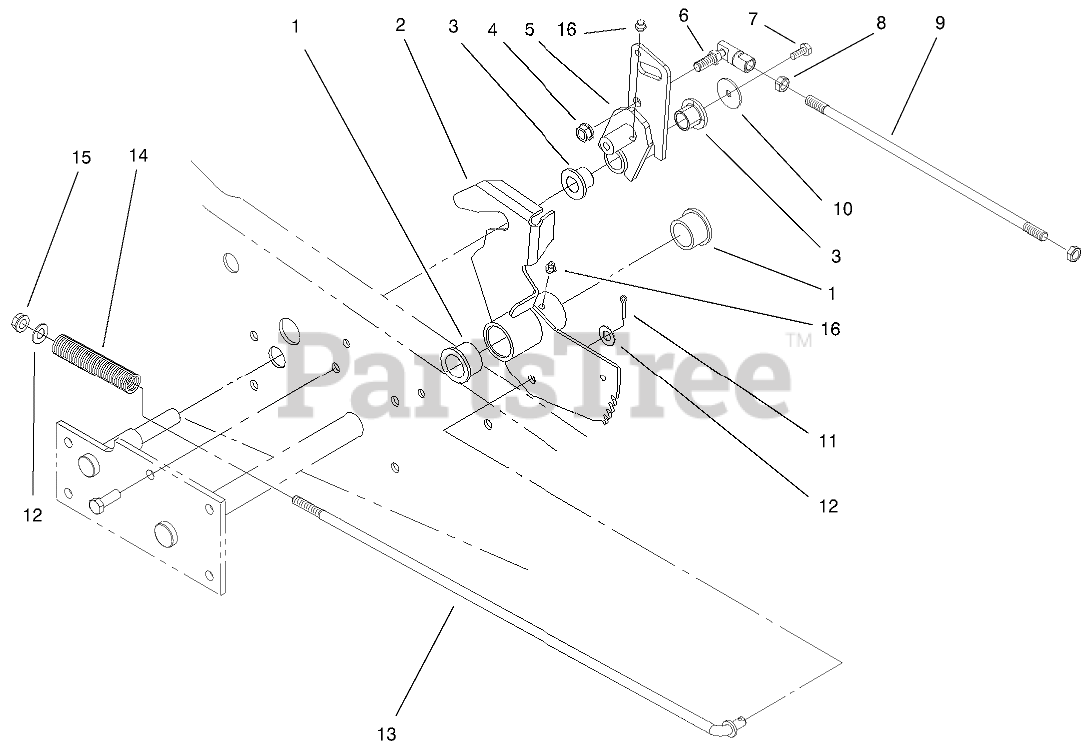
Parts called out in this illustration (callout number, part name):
1	BUSHING-FLANGED
2	PLATE-PIVOT, BRAKE
3	BUSHING
4	NUT-LOCK
5	PIVOT-HYDRO
6	END-TIE ROD, LH
7	SCREW-HH
8	NUT-JAM, LH
9	ROD-PIVOT TO PEDAL
10	WASHER-FLAT
11	PIN-COTTER
12	WASHER-FLAT
13	ROD-BRAKE
14	SPRING-COMPRESSION
15	NUT-LOCK, NI
16	FITTING-GREASE
